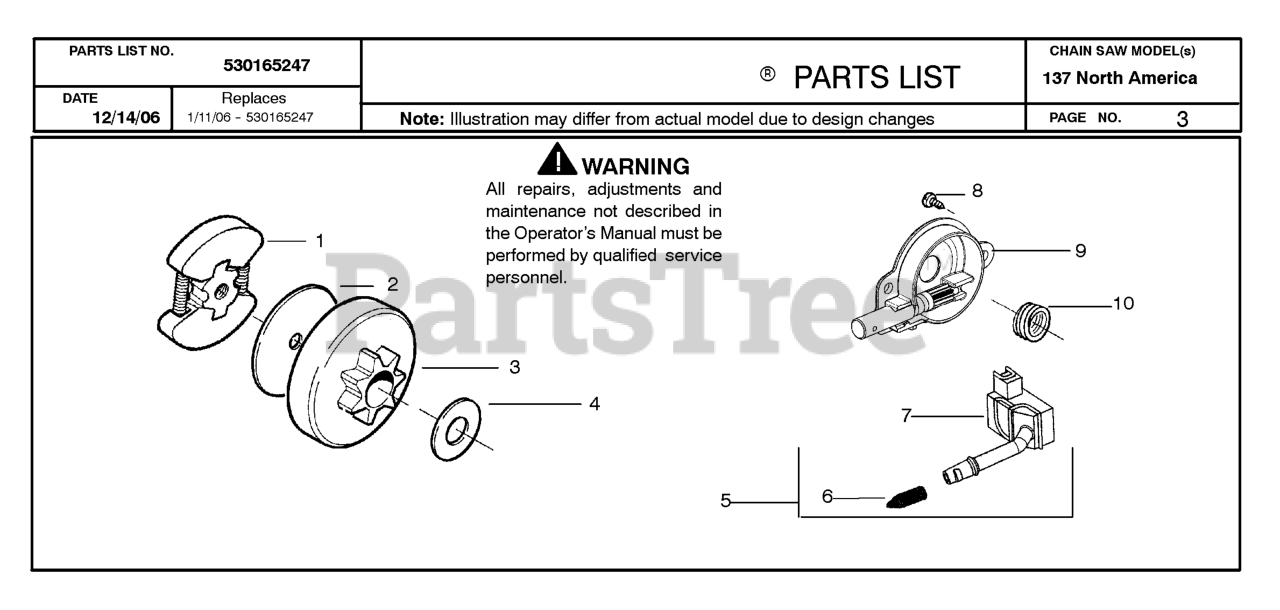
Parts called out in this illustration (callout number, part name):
1	CLUTCH ASSEMBLY
2	FRICTION DISC,CLUTCH 36/41
3	CLUTCH DRUM ASSY
4	THRUST WASHER
5	OIL PICKUP
6	SCREEN/FILTER
9	OILER ASS'Y 36/41
10	OILER GEAR 36/41
